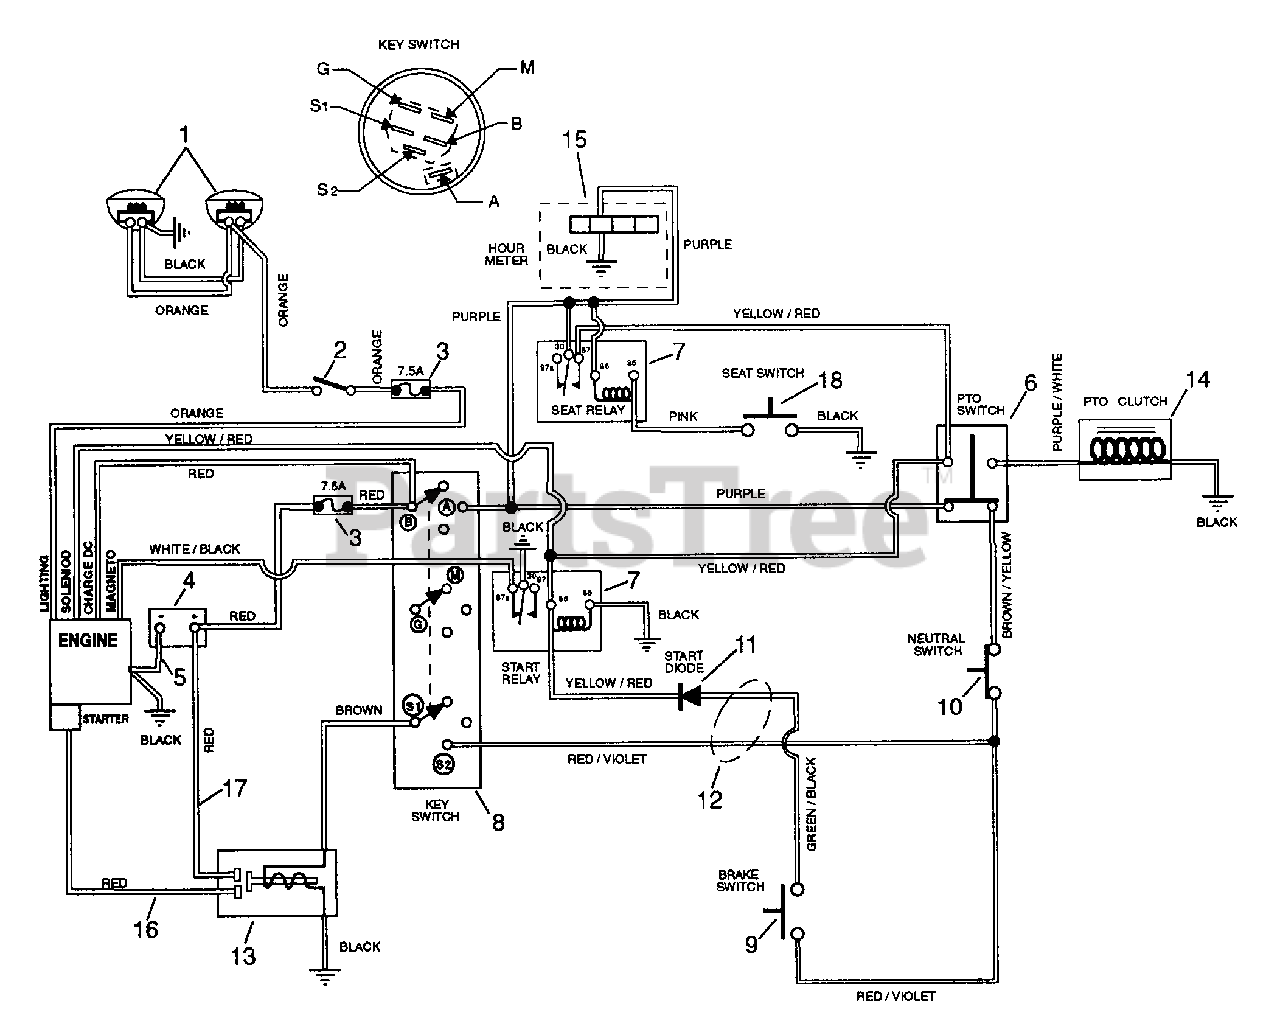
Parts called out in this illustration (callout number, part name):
1	HEADLIGHT- RH
1	HEADLIGHT- LH
2	SWITCH - LIGHT
3	7.5 AMP Fuse
4	BATTERY W/TUBE
5	GROUND CABLE .31X22.00X.31
6	PTO KNOB/ SWITCH ASSY
7	RELAY
8	KEY SWITCH
9	SWITCH- SINGLE POLE N.O.
10	SWITCH, NEUTRAL START N.C.
11	MOLDED DIODE PLUG 1 AMP
12	WIRE HARNESS - 1440G B&S
13	SOLENOID
14	ELECTRIC CLUTCH/BRAKE(1.8AMP)
15	HOURMETER KIT- SIERRA
16	START CABLE 22"
17	STARTER CABLE 6.75"
18	SWITCH- SEAT
